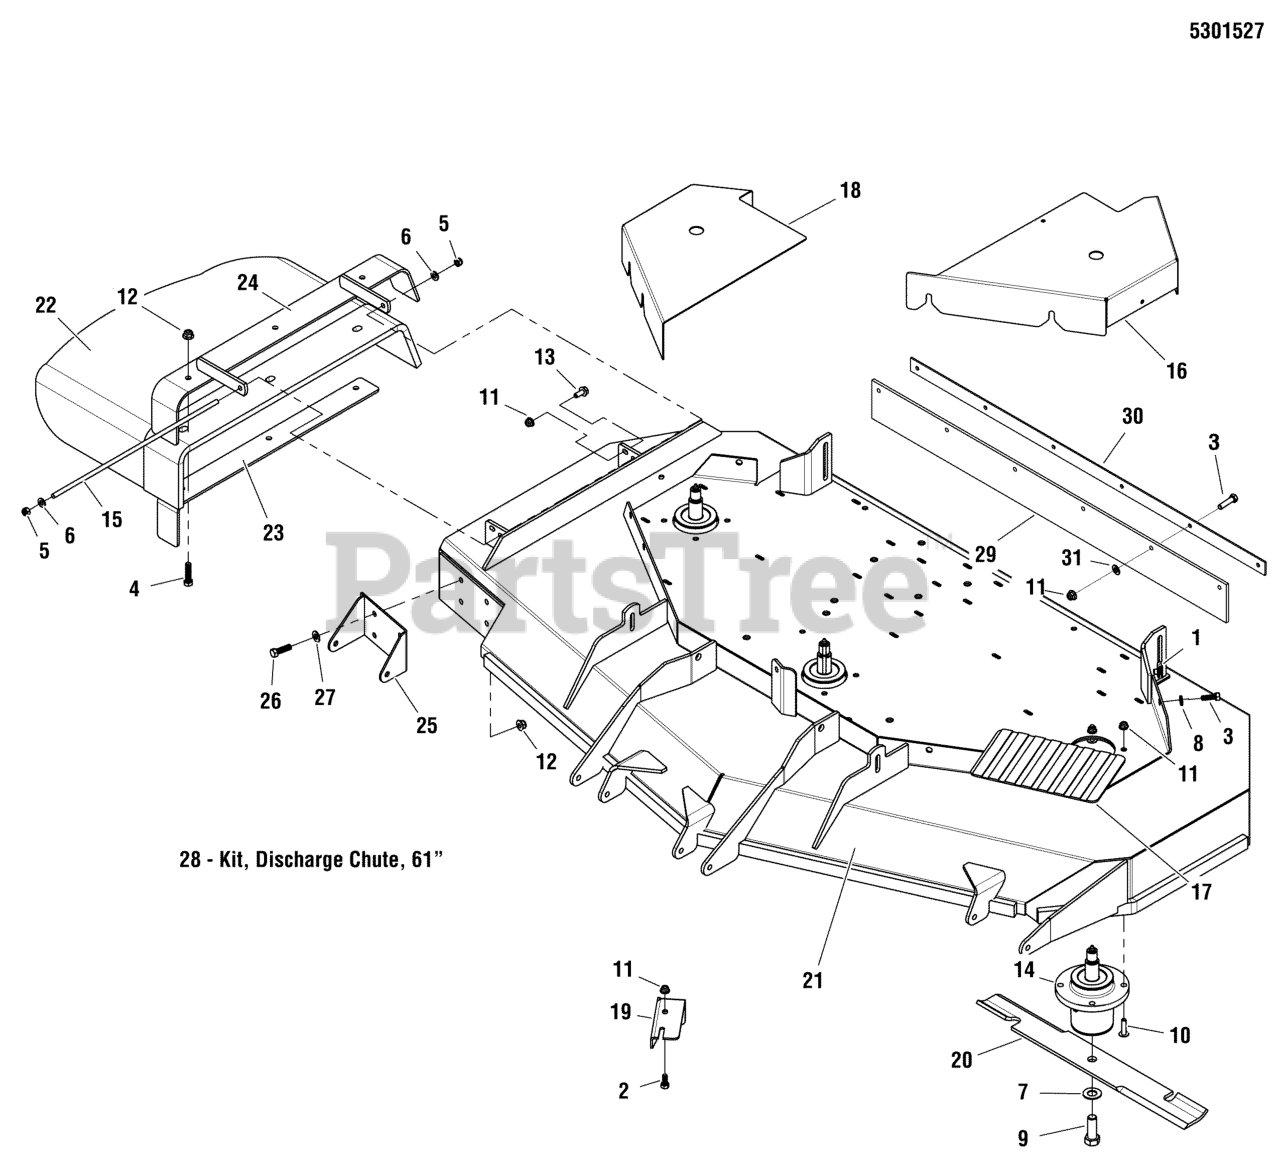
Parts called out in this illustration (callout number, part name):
1	BODY CLIP, 5/16-18-7GA MATERIAL
2	BOLT, 5/16-18 X 3/4, CARRIAGE
3	BOLT, 5/16-18 X 1 GD5 YZ
4	BOLT, 3/8-16 X 1-1/2" GD5 CZ
5	NUT, 5/16-24 HEX NYLON LOCK
6	WASHER, 5/16" SAE
7	WASHER, 5/8 GRADE 8, YZ
8	WASHER, 5/16" SAE
9	BOLT, 5/8-11 X 1-3/4 GD8
10	BOLT, 5/16-18 X 1 1/4 FLANGE
11	NUT, 5/16-18 HEX NYLOCK FLANGE
12	NUT, 3/8-16 HEX NYLOCK FLANGE
13	BOLT, 5/16-18 X 3/4 GD5
14	ASSM, SPINDLE, LOW PROFILE
15	ROD MOUNT, CHUTE 61"
16	GUARD, 61 - LH - RED
17	SAFETY WALK, 9.75 X 6.00
18	GUARD, 61 - RH - RED
19	PLATE, DEFLECTOR - BLK
20	BLADE SET, 61 DECK (3)
21	DECK SHELL W/ DECALS, 61"
22	CHUTE, DISCHARGE, BEND RUBBER (SV)
23	SUPPORT, DISCHARGE CHUTE, 61/72 - BLK
24	WELD, FRAME CHUTE, 61 - BLK
25	PLATE, BRACKET, ANTI SCALP - RED
26	BOLT, 3/8-16 X 1-1/4" GD5 CZ
27	WASHER, 3/8 SAE
28	PURCHASE INDIVIDUAL REPLACEMENT PARTS
29	FLAP, STRIPER, 61 DECK
30	PLATE, SUPPORT - BLK
31	5/16 PUSH-ON NUT RETAINER, STL, CZ
